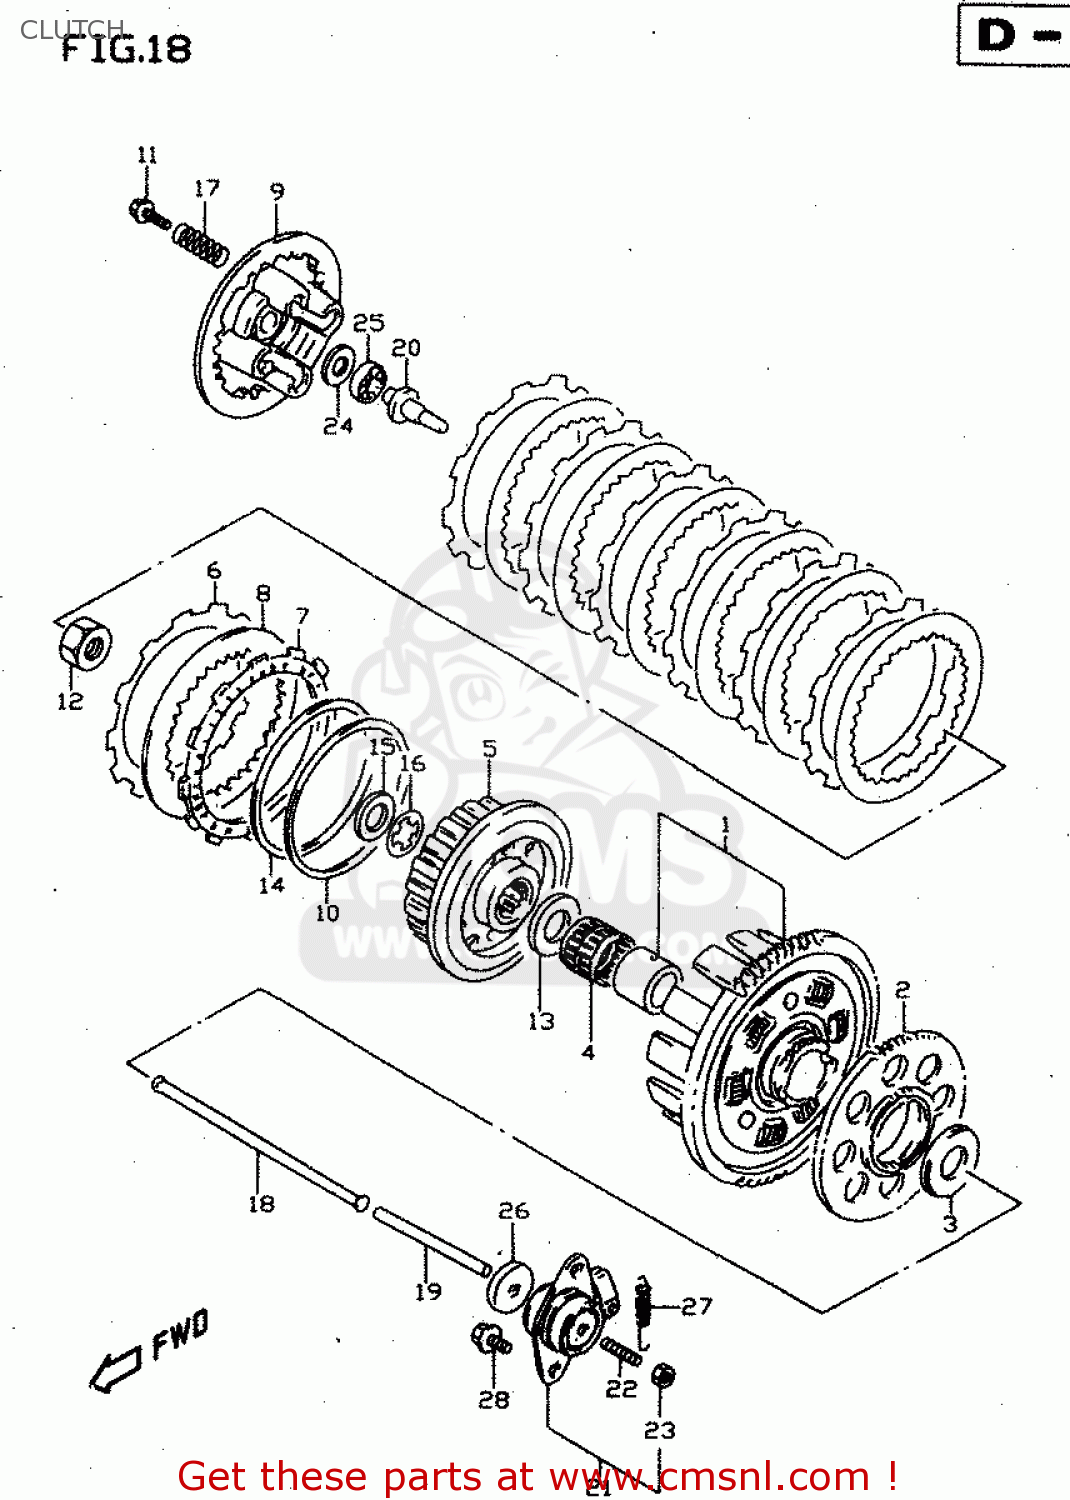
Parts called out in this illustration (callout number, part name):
1	GEAR ASSEMBLY,PRIMARY DRIVE
2	GEAR,GENERATOR DRIVE
3	WASHER(25X54X2.5)
4	BEARING(35X40X35.8)
5	HUB,CLUTCH SLEEVE
6	PLATE,CLUTCH DRIVE NO.1 (NAS)
7	PLATE,CLUTCH DRIVE(T:3.5) (NAS)
8	PLATE,CLUTCH DRIVEN (NAS)
9	DISC,CLUTCH PRESSURE
10	SEAT,WAVE WASHER(T:1.4)
11	BOLT(6X20)
12	NUT
13	WASHER(25X50X2.5)
14	WASHER
15	WASHER
16	SHIM(22X36X1)
17	SPRING
18	ROD,CLUTCH PUSH,R
19	ROD,CLUTCH PUSH,L
20	PIECE,CLUTCH PUSH
21	SCREW ASSY,CLUTCH RELEASE
22	SCREW(6X25)
23	NUT
24	WASHER(15.5X28X1)
25	BEARING(15X28X2)
26	SEAL,OIL(6X34X5.5)
27	SPRING
28	BOLT
